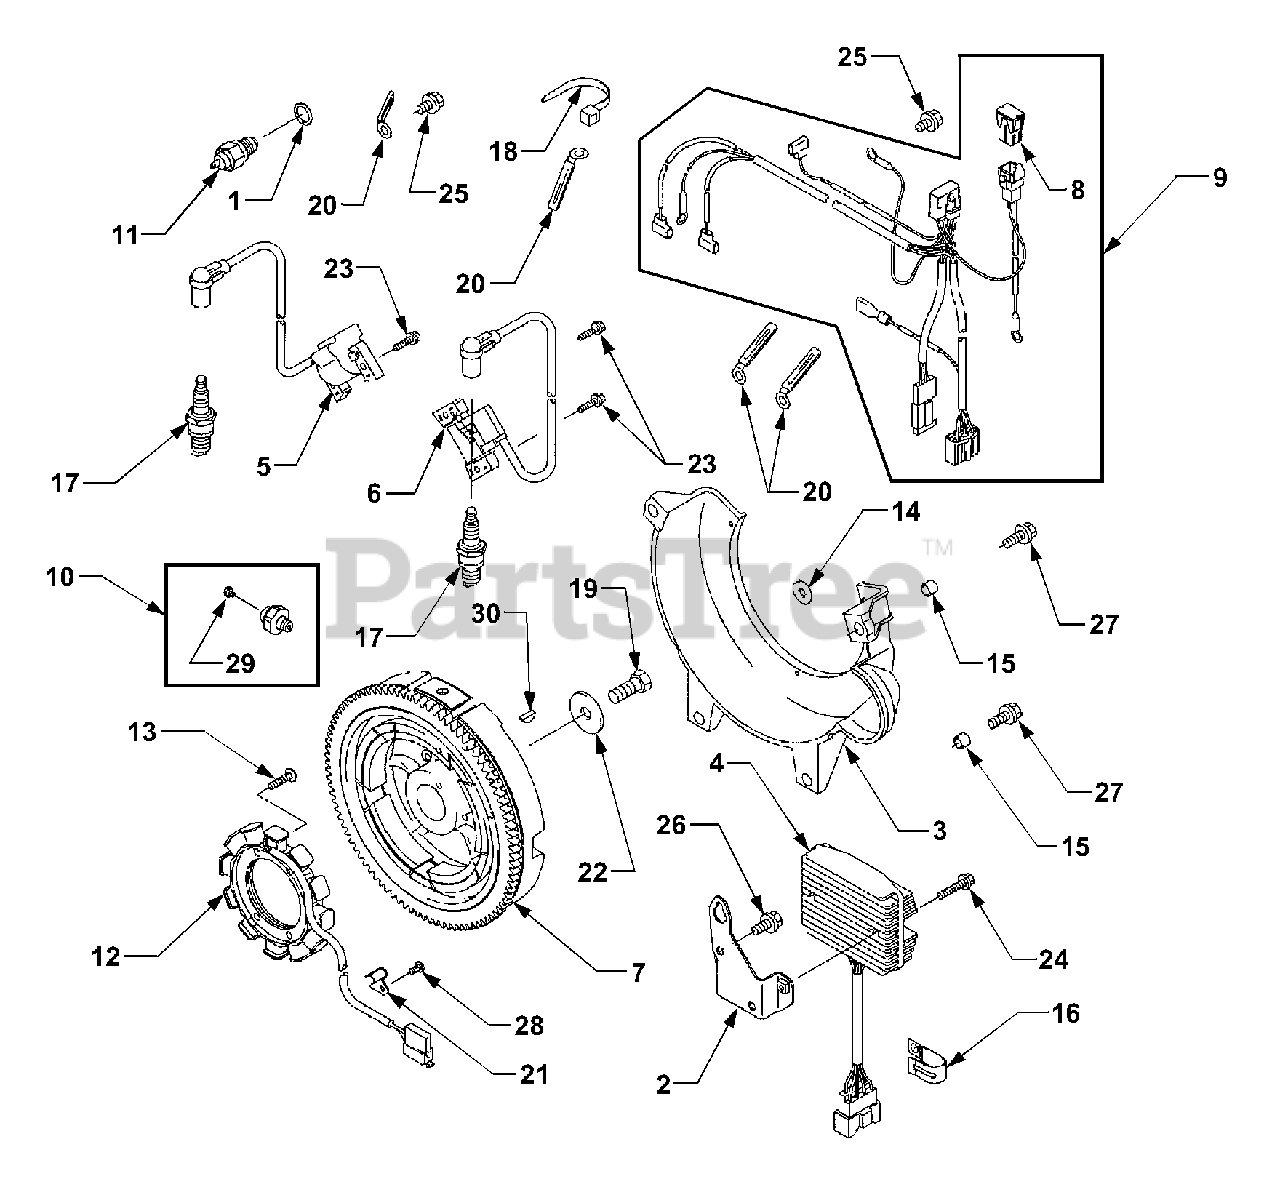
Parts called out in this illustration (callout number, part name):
3	Cover, Flywheel
4	Regulator, Voltage
5	Coil, Ignition, No. 1
6	Coil, Ignition, No. 2
7	Flywheel Assembly
9	Harness
10	Switch
12	Coil, Charging
15	Collar, 8.3 x 11.5 x 9
17	Plug, Spark
19	Bolt, 12 x 30
22	Washer, 12.2 x 40 x 3.0
23	Bolt, Flanged
24	Bolt, Flanged
25	Bolt, Flanged
26	Bolt, Flanged
27	Bolt, Flanged
30	Key, Woodruff
